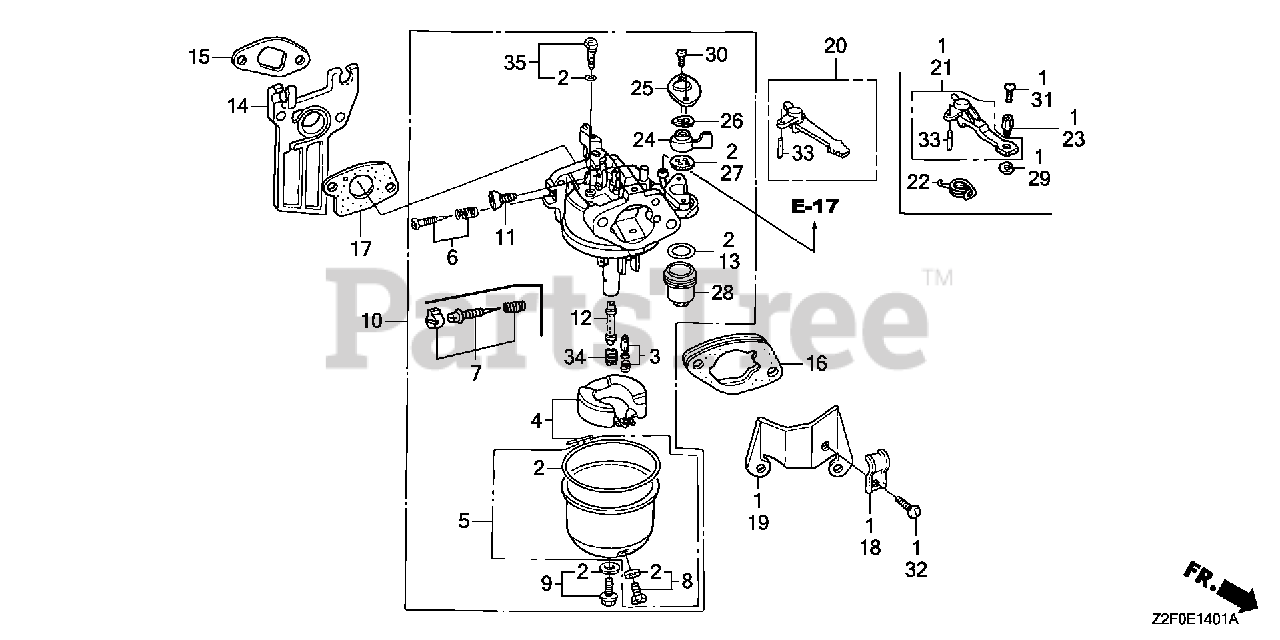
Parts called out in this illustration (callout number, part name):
1	CHOKE KIT, REMOTE CONTROL
2	GASKET SET
3	VALVE SET, FLOAT (SEAT NOT INCLUDED)
4	FLOAT SET
5	CHAMBER SET, FLOAT
6	SCREW SET, PILOT (CARBURETOR NO.)
7	SCREW SET, PILOT (CARBURETOR NO.)
8	SCREW SET, DRAIN
9	SCREW SET
10	CARBURETOR ASSY. (BE11C B)
10	CARBURETOR ASSY. (BE11C C)
11	SCREW, THROTTLE STOP
12	NOZZLE, MAIN
13	GASKET, FUEL STRAINER CUP
14	INSULATOR, CARBURETOR
15	GASKET, INSULATOR
16	SPACER, CARBURETOR
17	GASKET, CARBURETOR
18	HOLDER, CONTROL CABLE
19	STAY, CHOKE CONTROL
20	LEVER, CHOKE (STD)
21	LEVER, CHOKE (REMOTE)
22	SPRING, RETURN
23	HOLDER, CABLE
24	LEVER, PETCOCK
25	PLATE, LEVER SETTING
26	SPRING, PETCOCK LEVER
27	GASKET, PETCOCK
28	CUP, FUEL STRAINER
29	CIRCLIP (5MM)
30	SCREW, PAN (3X6)
31	SCREW, PAN (4X8)
32	SCREW, PAN (5X8)
33	PIN, SPRING (2X12)
34	JET, MAIN (#62)
34	JET, MAIN (#65)
34	JET, MAIN (#68)
35	JET SET, PILOT (#38)
